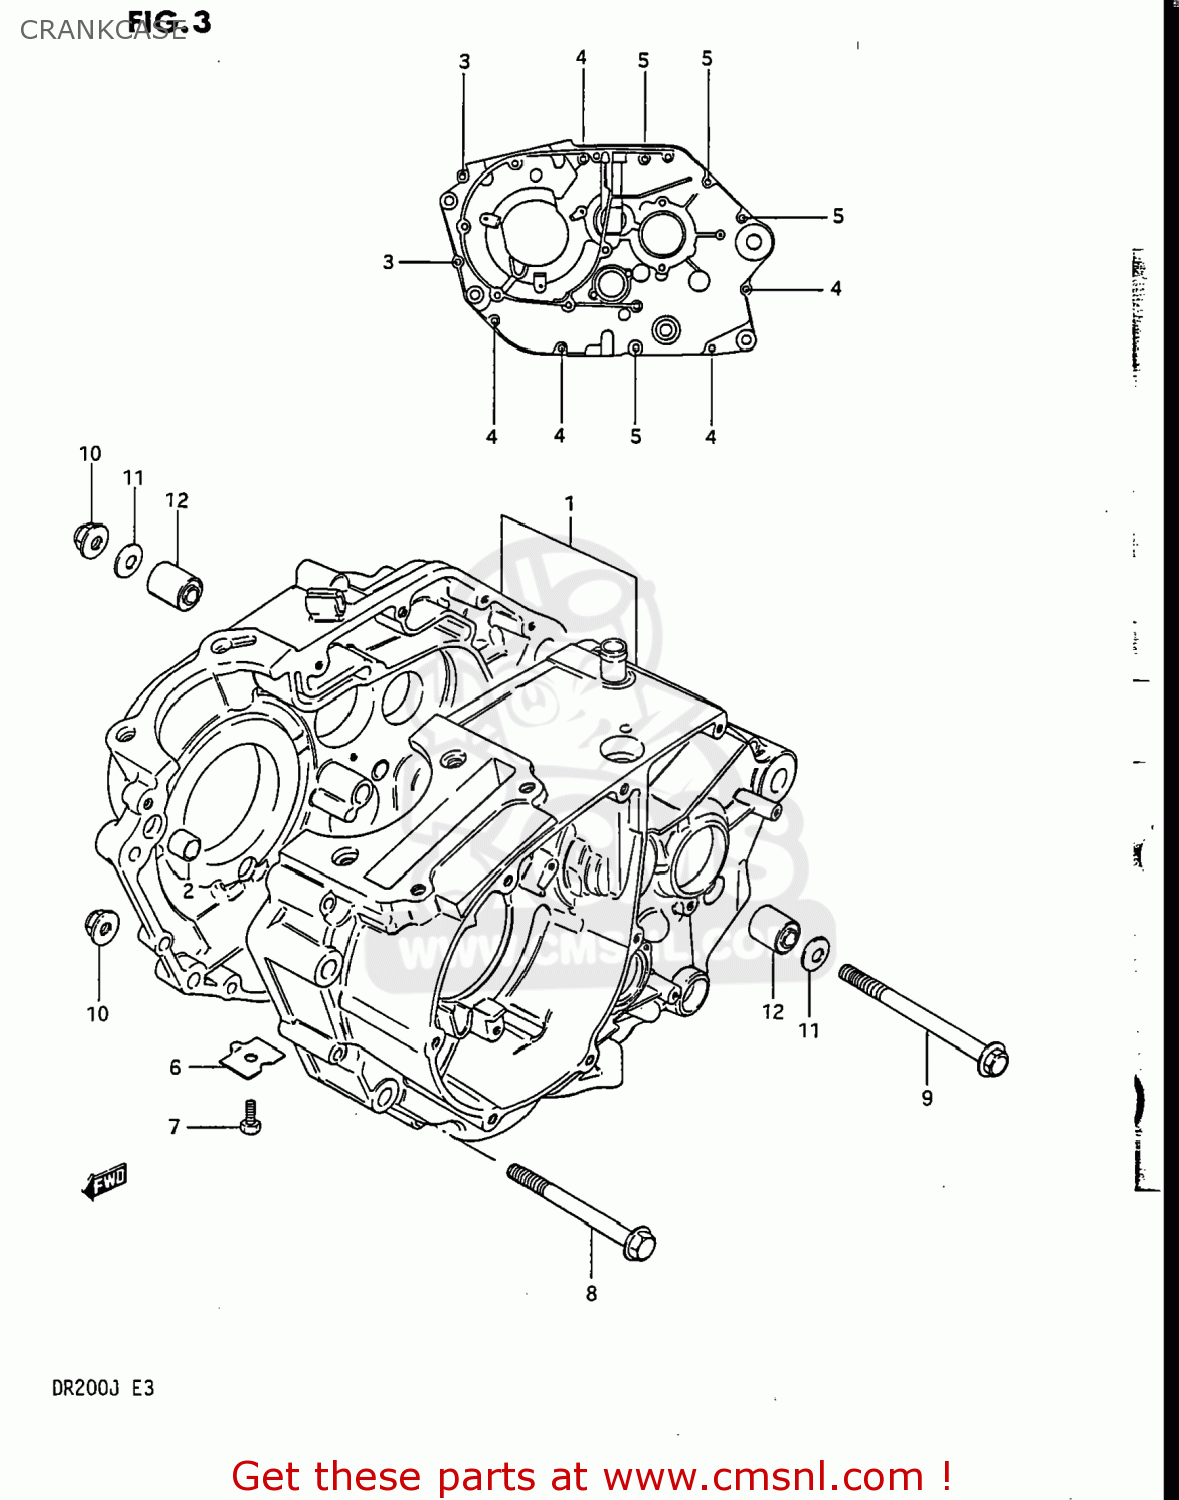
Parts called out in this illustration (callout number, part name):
1	CRANKCASE SET
2	PIN
3	BOLT
4	BOLT (6X60)
5	BOLT (6X75)
6	PLATE,OIL GALLERY PLUG
7	BOLT
8	BOLT(8X80)
9	BOLT L:115
10	NUT
11	WASHER
12	BUSH(8.4X18X16)
